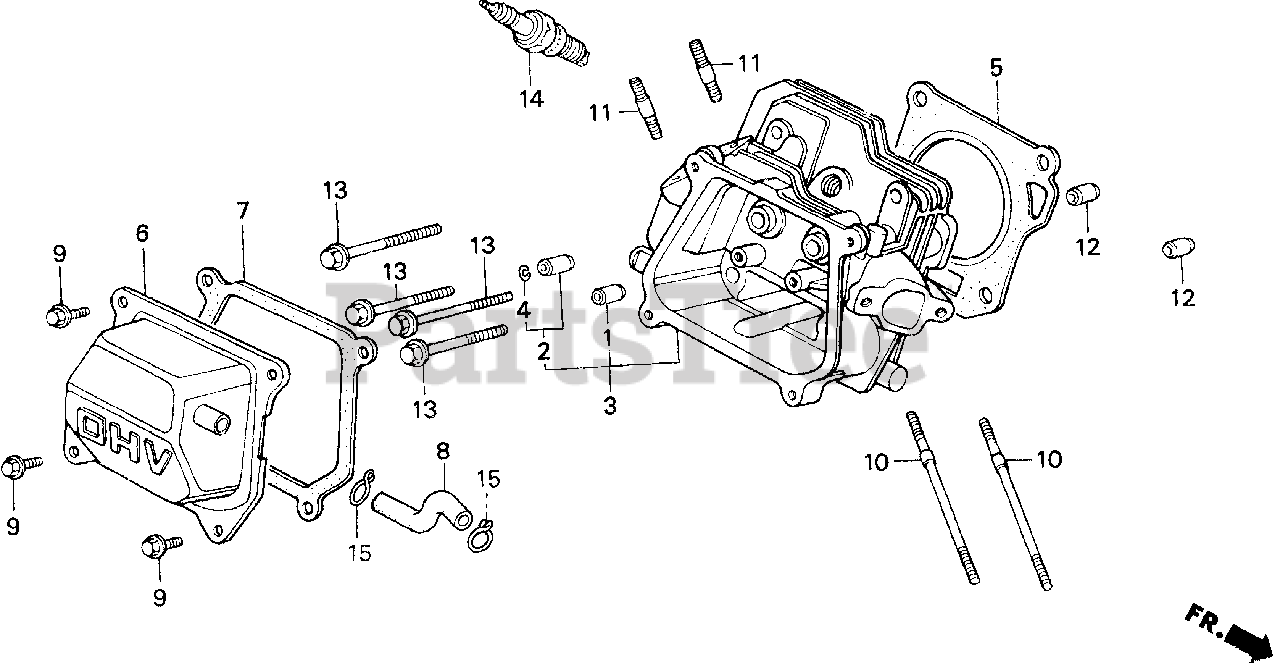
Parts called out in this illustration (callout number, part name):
1	GUIDE, VALVE (OS)
2	GUIDE, EX. VALVE (OS)
3	CYLINDER HEAD
4	CLIP, VALVE GUIDE
5	GASKET, CYLINDER HEAD
6	COVER, HEAD
7	GASKET, CYLINDER HEAD COVER
8	TUBE, BREATHER
9	BOLT, FLANGE (6X12) (CT200)
10	BOLT, STUD (6X109)
11	BOLT, STUD (8X32)
12	PIN A, DOWEL (10X16)
13	BOLT, FLANGE (8X60)
14	SPARK PLUG (BPR5ES) (NGK)
14	SPARK PLUG (W16EPR-U) (DENSO)
14	SPARK PLUG (BPR6ES) (NGK)
14	SPARK PLUG (W20EPR-U) (DENSO)
